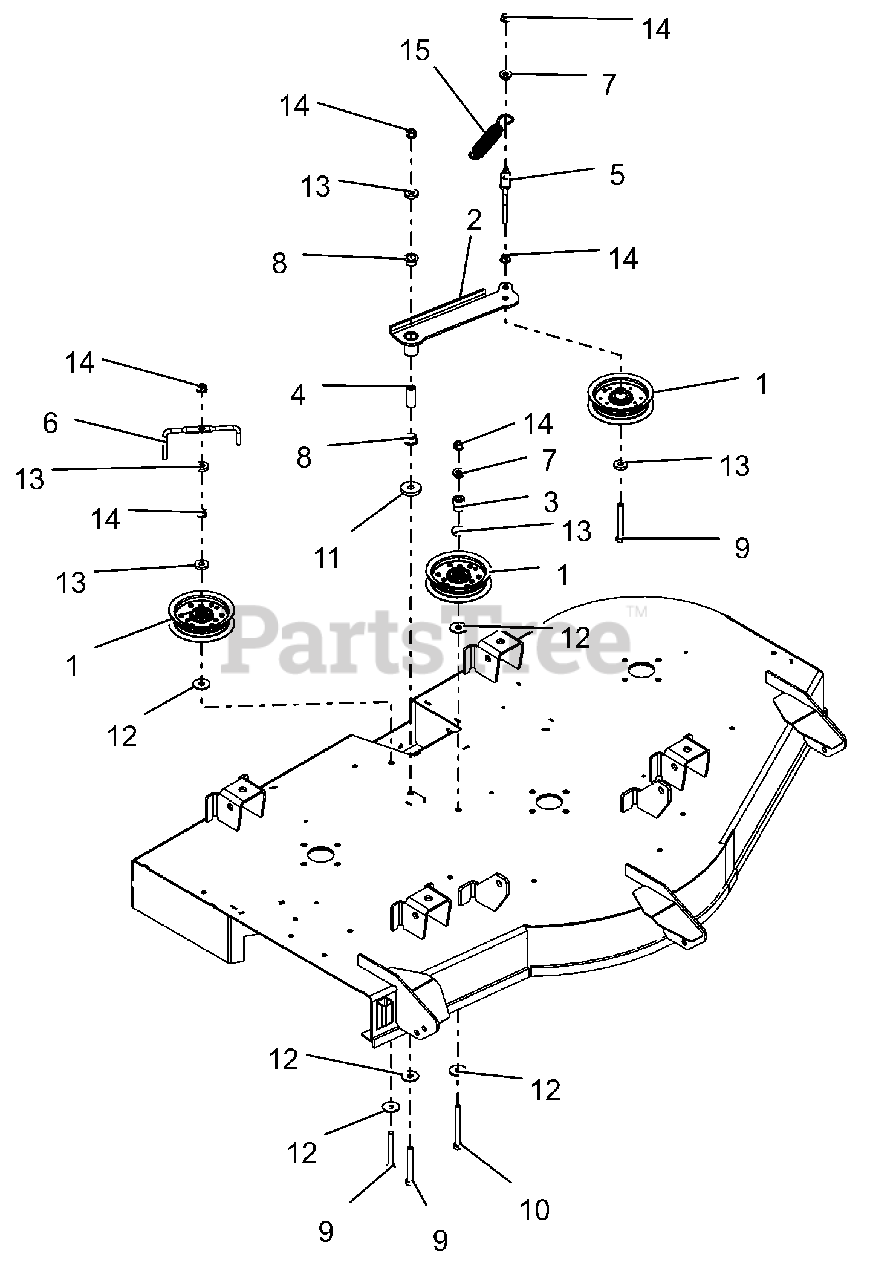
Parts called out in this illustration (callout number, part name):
1	ASM, IDLER 4"
2	WLDMT, IDLER ARM-52"
3	BUSHING, IDLER (P/M)
4	SPACER, .375IDX.625ODX1.66 PM
5	WIREFORM, BELT FINGER
6	WIREFORM, BELT FINGER
7	BSHG-FLG .385X.500X.875X.406
8	BSHG-FLG, .625X.750X.500X1.00
9	BLT, HEX .38-16X3.00F G5 ZCC
10	BLT, HEX .38-16X3.50 G5 ZCC
11	WSHR, FLT .406X1.50X.245 ZCC
12	WSHR FL STL .406X1.25X.10ZC120
13	WSHR, FLT .406X1.00X.188 ZCC
14	NUT-LK-CTR-FLG .375-16 GF ZCC
15	SG-TENS .135X.98X6.0 WLD 62
